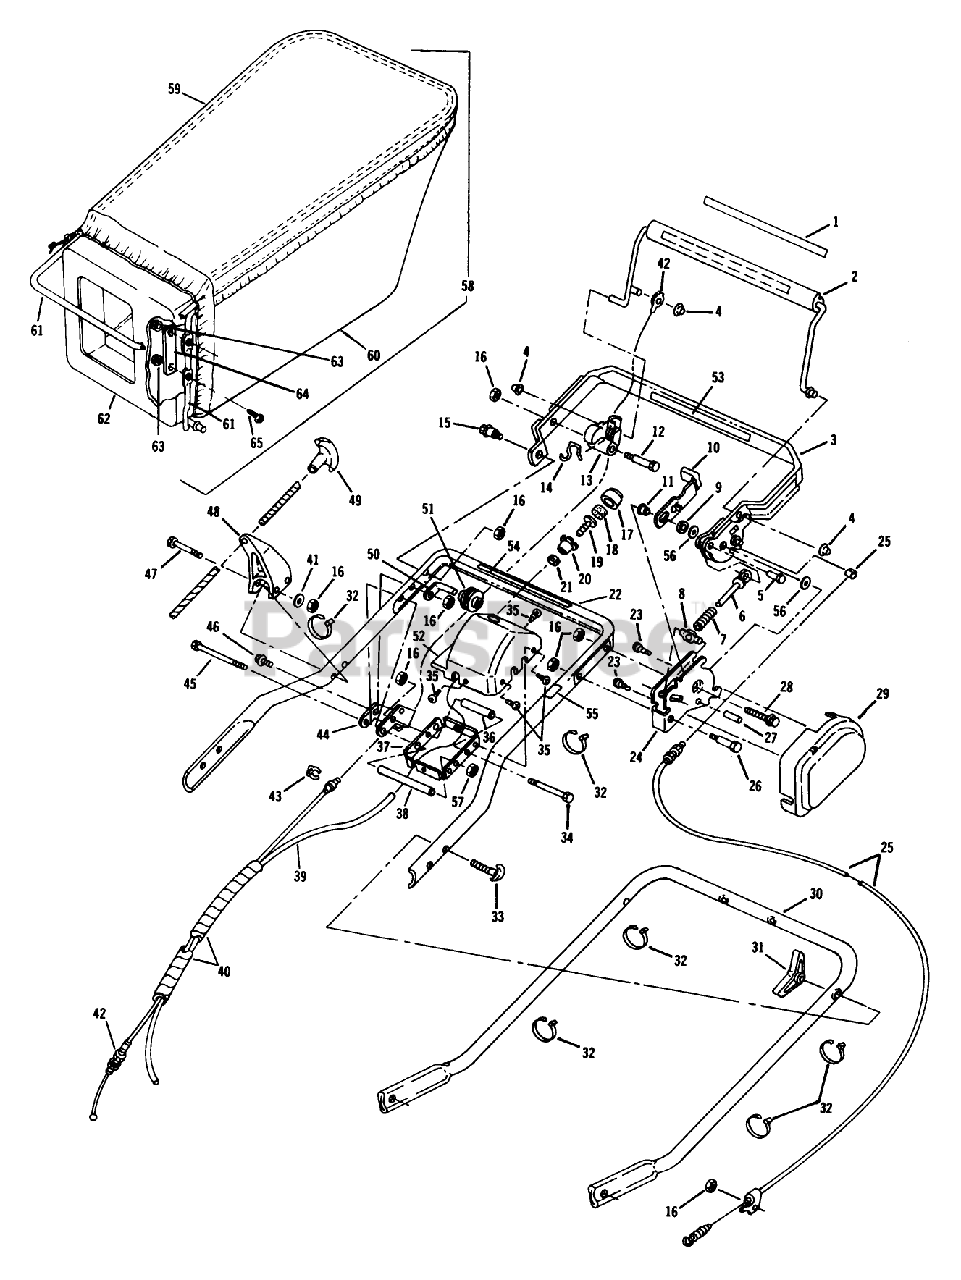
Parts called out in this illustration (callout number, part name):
9	WASHER M
14	Retainer-Cable to Cam
16	LOCKNUT E
18	FILTER S
21	LOCKNUT S
25	CABLE ASM
31	NUT-WING
33	BOLT QUALITY
35	SCREW F
43	RET. RING
45	BOLT-CONSOLE
49	HANDLE,STARTER
59	HANGER BAG TROX
62	BAG ADAPTOR PL
63	LOCKNUT E
